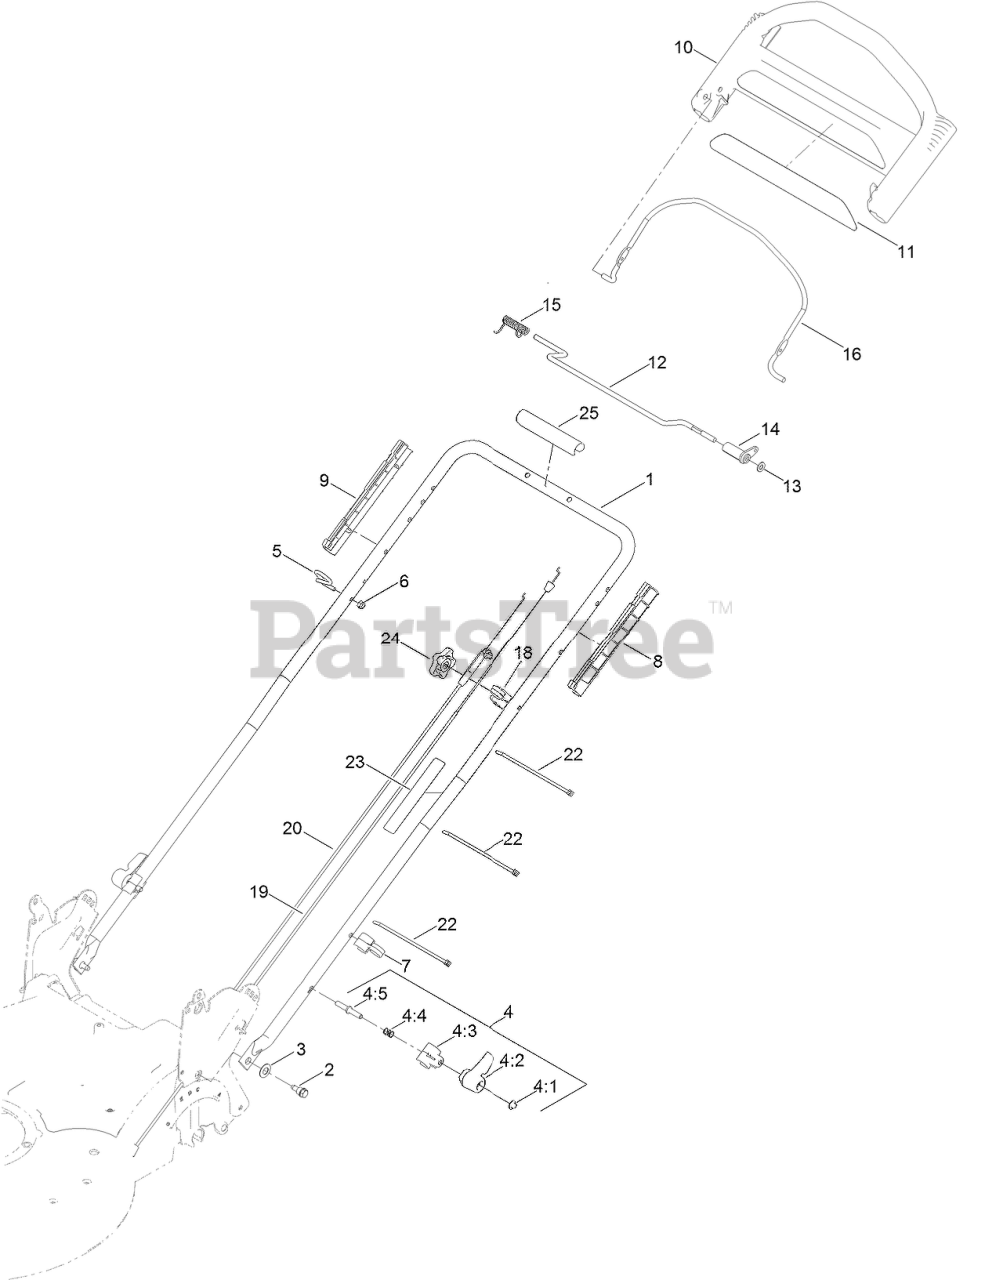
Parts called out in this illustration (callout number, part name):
2	BOLT-SHOULDER
3	WASHER-SPRING, CONICAL
4	QUICK RELEASE ASM
4:1	NUT-PUSH
4:2	LEVER
4:3	ANCHOR-SPRING
4:4	SPRING-COMPRESSION
4:5	ROD-RELEASE
5	GUIDE-ROPE
6	NUT-LOCK, NI
7	GUIDE-CABLE
8	GUIDE-LH
9	GUIDE-RH
10	HANDLE-CONTROL
12	BAR-CONTROL, TRACTION
13	WASHER-PLAIN
14	LEVER-TRACTION
15	Spring-Torsion
16	BAIL-BRAKE
18	ANCHOR-CABLE
19	CABLE-TRACTION
20	CABLE-BRAKE
22	TIE-CABLE
23	DECAL-TRACTION, ADJUST
24	KNOB-HANDLE, LOCKING
25	HANDLE-COVER
